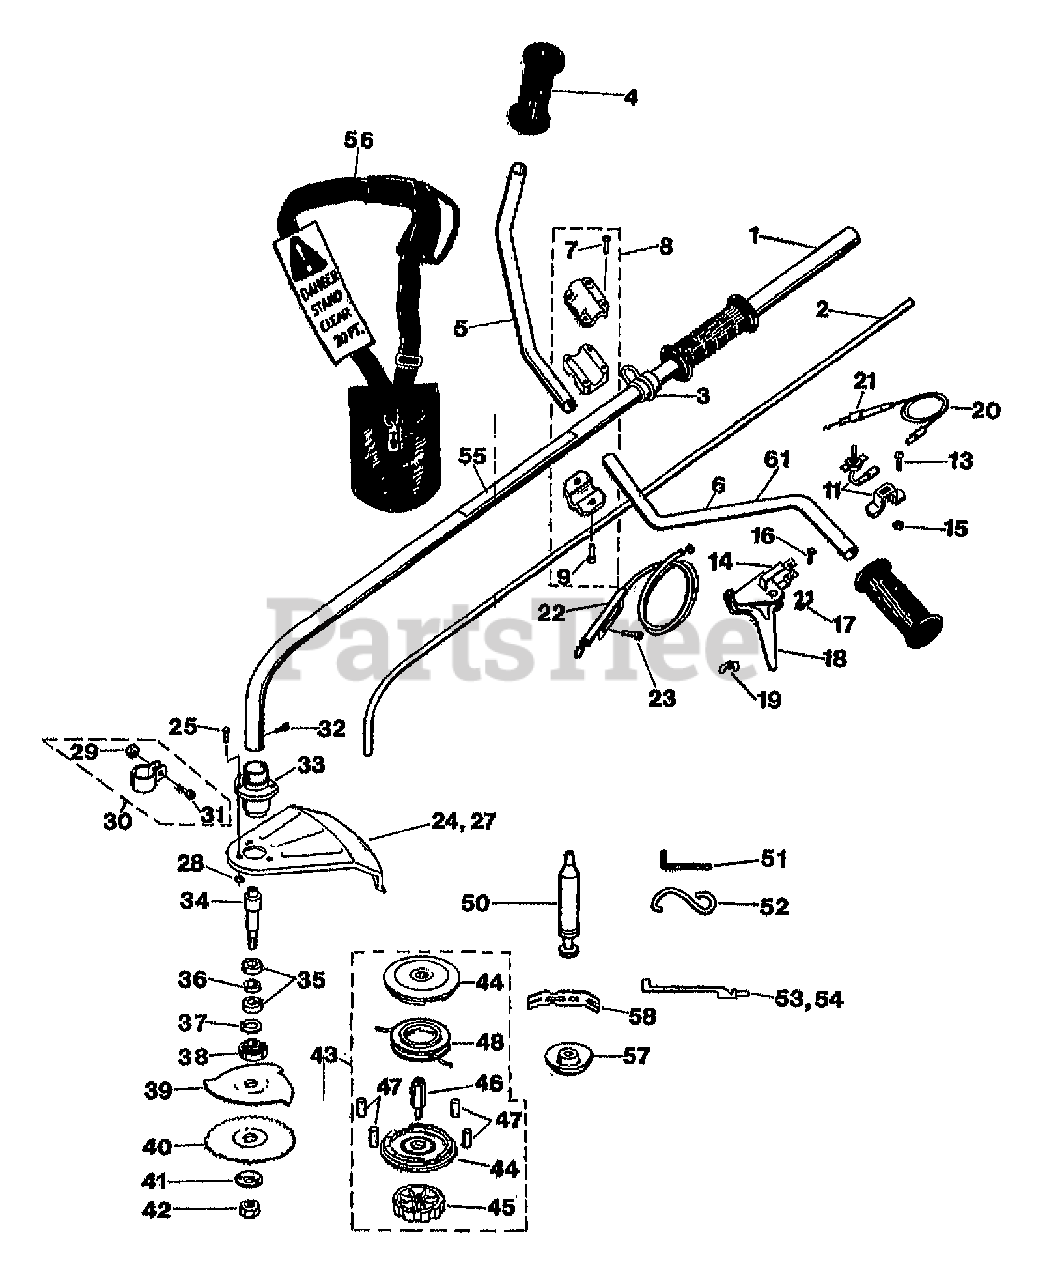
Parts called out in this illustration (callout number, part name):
1	HSG-DRIVESHAFT W/GRIP
2	SHAFT-DRIVE 5/16X57"
3	ASSM-SWIVEL
4	GRIP-HANDLEBAR
5	H/BAR-RH W/GRIPS
6	HANDLEBAR-LH W/GRIP
7	SCR-HXSKT 1/4-20X.75
8	ASSM-CLAMP (incl. 7 & 9)
9	SCREW, SOCKET HEAD, 10-32, HANDLEBAR CLAMP
11	SWITCH-ON/OFF (INCL. BRACKET)
13	SCR-PHP M10-32X.75 ZP
14	KIT-CLAMP TRG. H205596
15	NUT-HH M10-32X.125
16	SCREW, HEX HD 10-32X1, THROTTLE CONTROL
17	SPRING, THROTTLE CONTROL
18	ASSM-TRIGG H205532 (INCL. 16,17,19)
19	NUT, WING, 10-32, THROTTLE CONTROL
21	WIRE CONNECTOR & COVER
22	CABLE-THROTTLE
23	SCR W/SERRATED WASHER
24	SHIELD-GRASS (INCL. 25,27,28)
25	SCR.& NUT
27	SHIELD-GRASS
28	KIT-HDW DUSTSHIELD
29	NUT-HF/LK 1/4-20 ZP
30	CLAMP, LOWER HEAD
31	SCR-HXSKT 1/4-20X.75
32	SCR #10-32X5/16
33	ASSM-LOWER HEAD
34	ARBOR-LOWER (SQUARED)
36	ASSM-LOWER HEAD SPACER
37	RING-RETAINING
38	WASHER-CUP
39	BLADE-8" TRIKUT HOFFCO
40	BLADE-8" BRUSHCUTTER
41	WASHER-ARBOR 3/8
42	NUT W/NYLON INSERT 3/8-24
43	MONOFILAMENT HEAD-2 LINE (INCL. 44-48)
44	HOUSING-MONOFILAMENT HEAD
45	KNOB-RH MONOFILAMENT HEAD
46	ARBOR-MONOFILAMENT HEAD
47	LINE SAVER-MONOFIL HEAD
48	SPOOL-15'H2 #H211524
50	GUN-GREASE
51	WRENCH-ALLEN 3/16
52	LOWER HEAD TOOL
53	STRAP-TIE 7/8
54	STRAP-TIE 1"
55	DECAL-INST
56	HARNESS W/HIP PAD (FOR RIGHT HAND USE)
56	HARNESS-LEFT HAND
57	KIT-GLIDE BALL
58	TEMPLATE-GAUGE(FILING)
61	DECAL, MADE IN AMERICA
